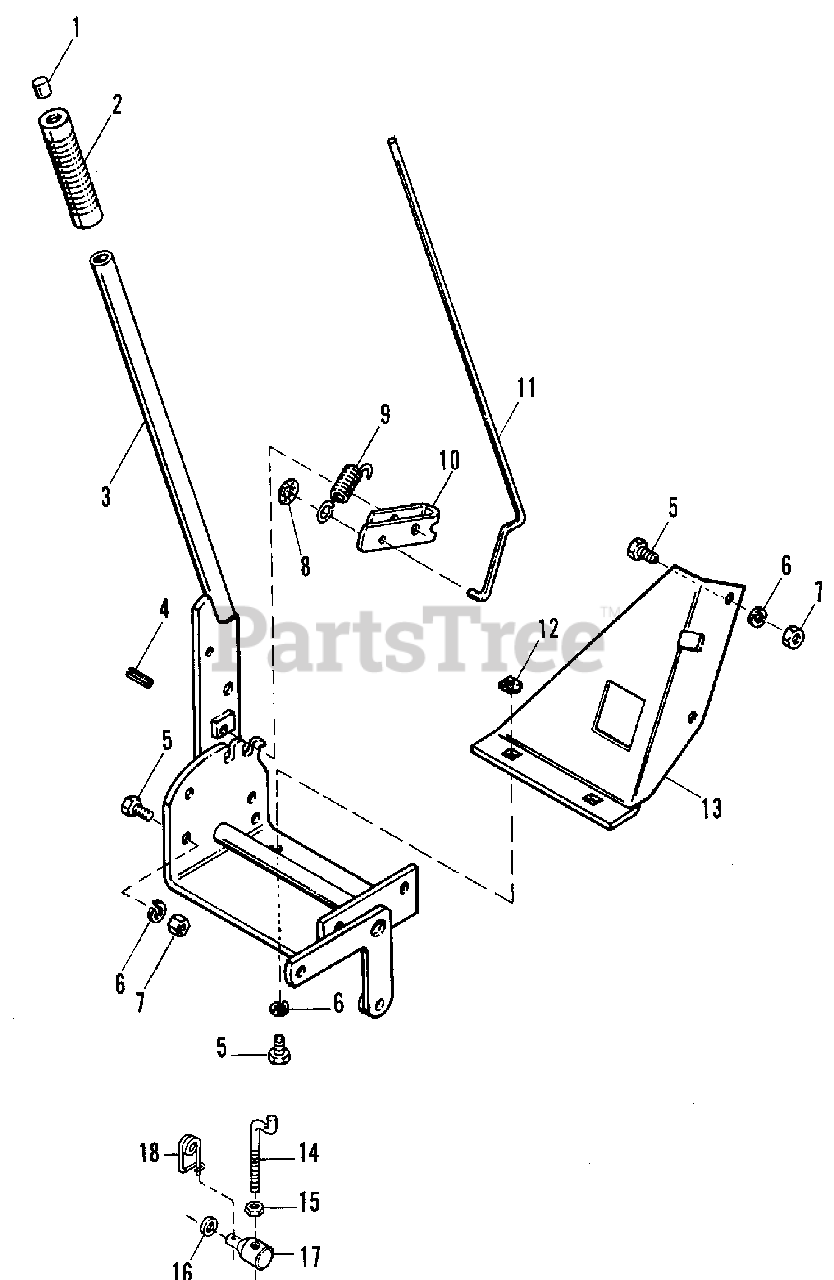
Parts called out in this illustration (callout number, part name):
3	LEVER ASSEMBLY
5	CAPSCREW, Hex Head., 5/16-18 x 3/4
6	LOCKWASHER, 5/16
7	NUT, Hex, 5116-18
10	LATCH, Lever
12	NUT, Speed, 5/16-18
13	BRACE, Lift Lever
15	NUT, Jam, 5/16-18
16	WASHER, 5/16
17	TRUNNION, Pivot
18	CLIP, Safety
